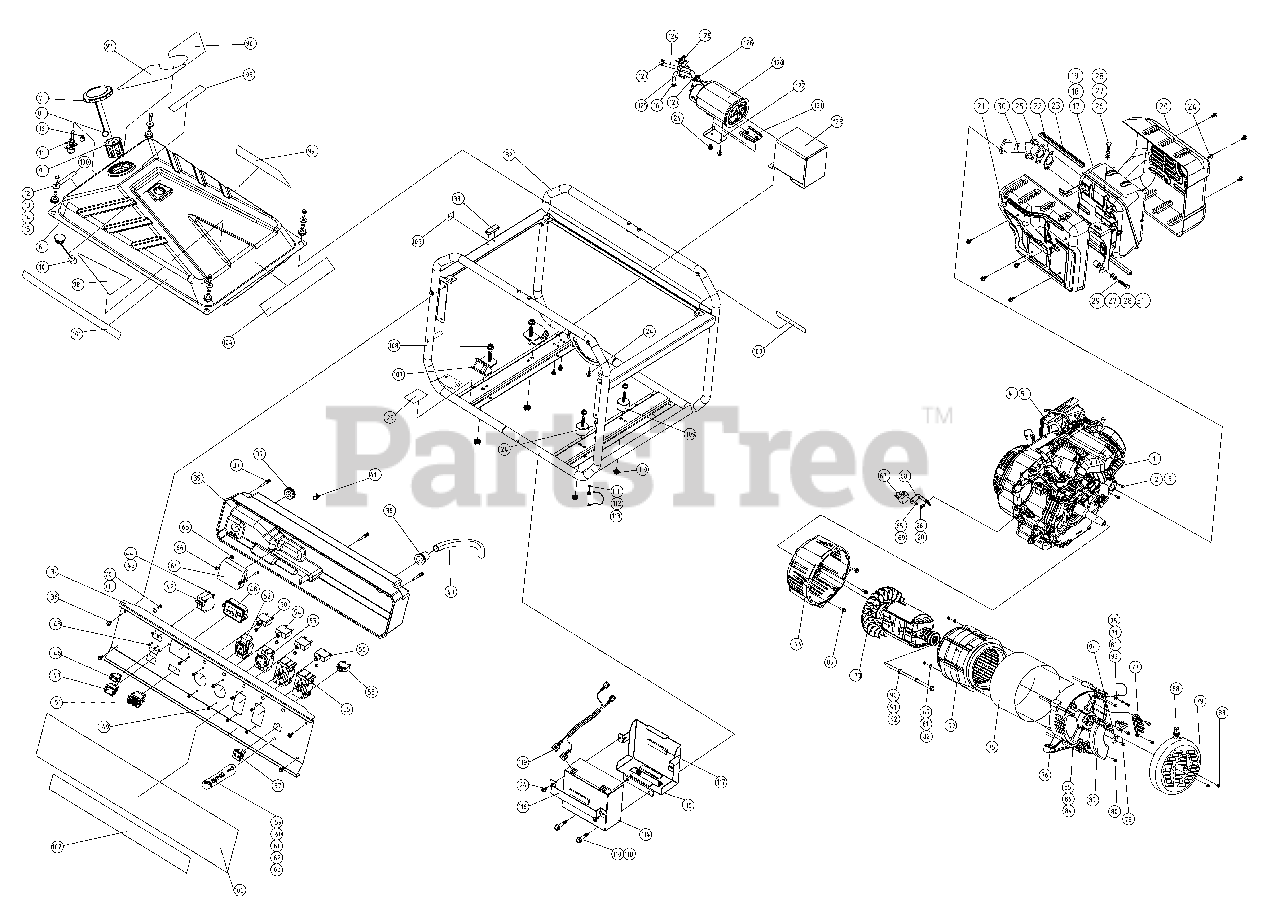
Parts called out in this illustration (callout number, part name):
1	CH395TF E3 KPP
2	GASKET, MUFFLER
3	NUT USE 25 086 240-S
4	LINE, FUEL (10"-CUT TO LENGTH)
5	CLAMP, FUEL LINE
6	TANK, FUEL
7	CAP ASSEMBLY - FUEL TANK (EPA)
8	RETAINER, TANK CAP PULL RING
9	FILTER , FUEL TANK
10	GUAGE, FUEL LEVEL ASSEMBLY
11	VALVE,FUEL SHUT OFF
12	SCREW, BOLT GB 5787-M6X20
13	MOUNT, FLAT GASKET GB/T 5287-6
14	SPACER, FUEL TANK BUSHING
15	SPACER, INNER RING
16	CLAMP, FUEL LINE 6
20	COVER, MUFFLER FRONT
21	COVER, MUFFLER BACK
23	MOUNT, RUBBER GASKET
24	SCREW, BOLT M6X12
25	SCREW, BOLT M8X22
26	SCREW, BOLT M8X20
27	WASHER, FLAT GASKET 8
28	WASHER, SPRING 8
29	SCREW, BOLT L35
30	MANIFOLD, MUFFLER PIPE ASSEMBLY
31	SPACER, MUFFLER BUSHING
33	DAMPER, HANDLE DAMPING PAD
34	PANEL (PRO5.2E)
36	SCREW, BOLT GB5789-M6X12
37	SCREW M5X45
38	GROMMET, POWER CORD SHEATH
39	GROMMET 16MM
40	SLEEVE BRAIDED SLEEVE 1
41	STRAP, CABLE TIES 3.2X120 (WHITE)
43	SCREW, M3X6
44	SCREW GB818-M4X8
45	WASHER, SPRING GB93-4
48	DIGITAL DISPLAY METER
49	SCREW M4X12
52	L 14-30 SOCKET
53	RECEPTACLE, NEMA L5-30R SOCKET
54	BREAKER, CIRCUIT 20A
55	RECEPTACLE, GFCI 20A/125V NEMA 5-20OR
56	BREAKER, CIRCUIT 20A
57	RECEPTACLE, DC SOCKET 12V8.3A
58	BREAKER, CIRCUIT DC 8A
59	SCREW, BOLT M6X25
61	WASHER, PLATE GASKET 6
62	WASHER, SPRING GASKET 6
64	MODULD, IDLE CONTROL
65	SCREW M5X16-GB818
67	RECTIFIER, BLOCK (PRO5.2E)
68	BRACKET, STATIONARY BARRIER
70	SCREW M5X12
71	WASHER, SPRING GB 93-5
72	STATOR ASSEMBLY
73	ROTOR ASSEMBLY (PRO5.2E)
76	CAP, BACK COVER
77	BOARD ASSEMBLY, PATCH
78	BRUSH, CARBON ASSEMBLY
80	SCREW, BOLT GB 5787-M5X16
81	WASHER, PLATE GT/T 95
82	SCREW, BOLT M5X205
83	SCREW, BOLT M5X10
84	SCREW BOLT M6X180
85	WASHER, PLATE GASKET 6
86	WASHER, SPECIAL SPRING 6
87	RECTIFIER AVR (PRO5.5E)
88	SLEEVE, MOTOR RUBBER SHEATH
89	SCREW BOLT 3/8-16X27MM
90	BOLT 5/16-24X222MM
92	WASHER, SPRING
93	BOLT GB/T 5783-M5X10
94	RETAINER, 12V DC CHARGE BRIDGE
95	WIRE, 10GA WHITE
96	DECAL, TANK BRAND, LEFT
100	DECAL, HOT_EXHAUST
101	CPSC DECAL_5.2
102	DECAL, OPERATING_PROCEDURE
104	DECAL, GENERATOR_WARNING
105	FUEL SWITCH DECAL
107	MOUNT, ENGINE ISO
109	MOUNT, RUBBER FOOT
111	GROUND WIRE
112	SPACER, FLOWER SHAPED GASKET
114	KIT, BATTERY RACK 12V18AH
115	SUPPORT, BATTERY MOUNTING ASSEMBLY
116	BRACKET, BATTERY
117	DAMPER - DAMPING STRIP
118	SCREW, BOLT M8X40
119	HARNESS ASSEMBLY, WIRING
120	CARBON CANISTER
121	PLATE, CARBON TANK HOLDER (W/NUT)
122	PLATE, CARBON TANK HOLDER (NONE NUT)
124	HOSE, FUEL PIPE 2
125	FUEL HOSE, LOW PERMEATION
126	CLAMP, FUEL PIPE 5
127	CLAMP, FUEL PIPE 7
128	STRAP, CABLE TIES 7.7X150 8
